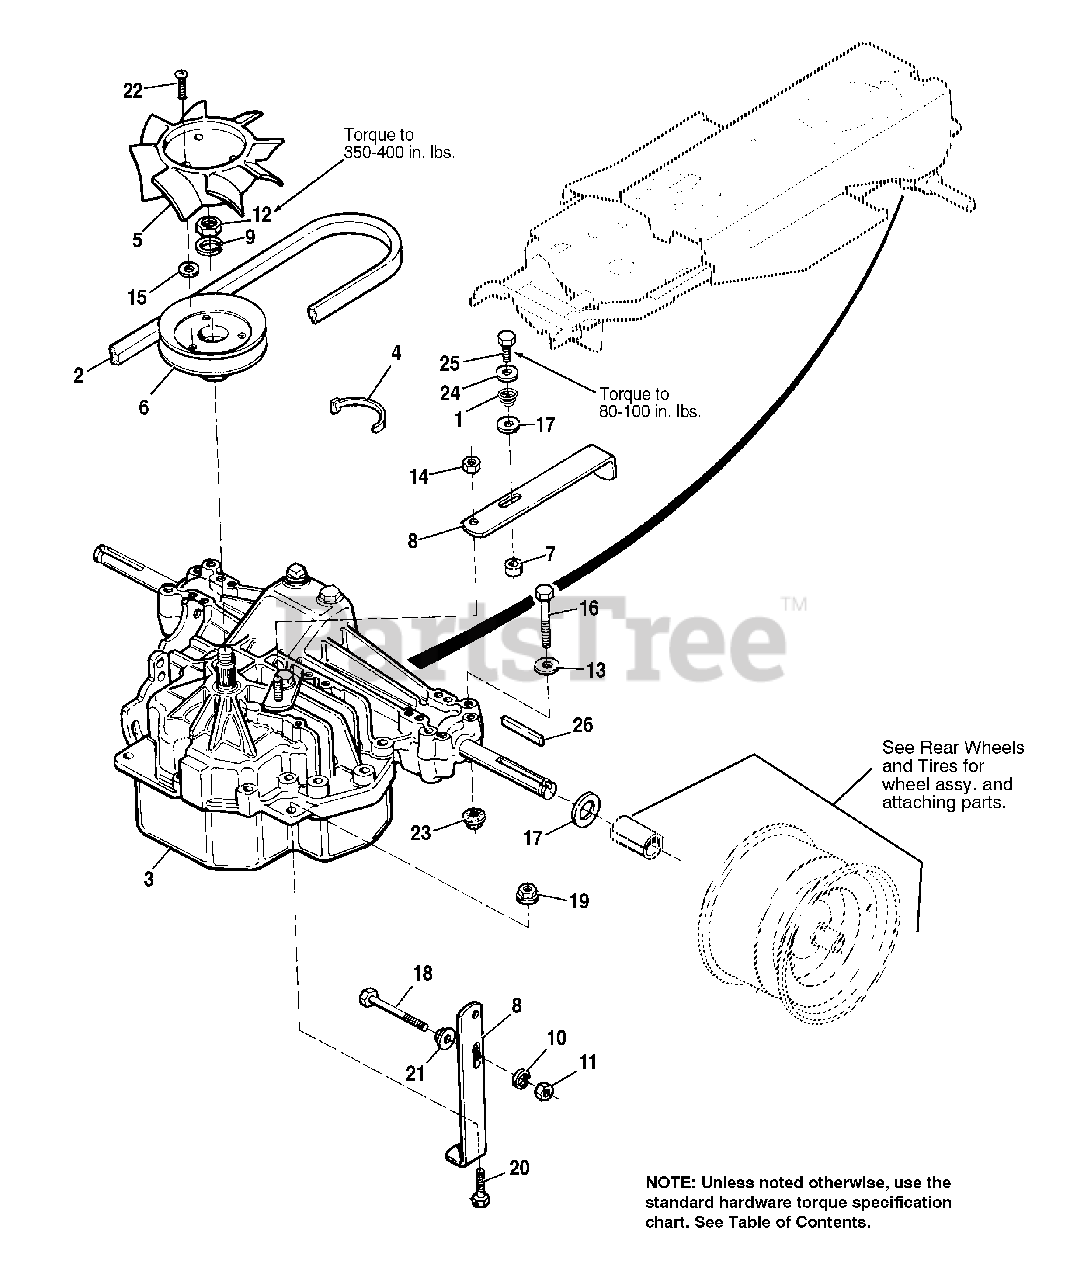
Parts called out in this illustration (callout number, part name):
1	SPRING, Conical
2	BELT, Drive
3	TRANSAXLE, Hydro Gear
6	PULLEY ASSY.
8	LEVER
9	LOCKWASHER, 1/2
10	LOCKWASHER, 5/16
11	NUT, Hex, Full, 5/16-18
12	JAM NUT, Hex, 1/2-20
13	WASHER, Plain, 5/16
14	NUT, Hex, Full, Lock, 1/4-20
15	WASHER, Plain, 1/4
16	CAPSCREW, Hex, 5/16-18 x 2-1/2
17	WASHER, 13/32 x 1-1/4 x 1/16
18	CAPSCREW, Hex, 5/16-18 x 3-1/4
19	NUT, Hex, Flange, Whiz, 5/16-18
20	CAPSCREW, Hex, Whiz, 5/16-18 x 1-1/4
21	NUT, Hex, Flange, Whiz, 5/16-18
22	SCREW, Taptite, 1/4-20 x 1-1/8
23	NUT, Hex, Flange, Lock, 5/16-18
24	WASHER, 1/4 x 1-1/4 x 1/16
25	SCREW, Taptite, #10-24 x 1-1/4
26	KEY
